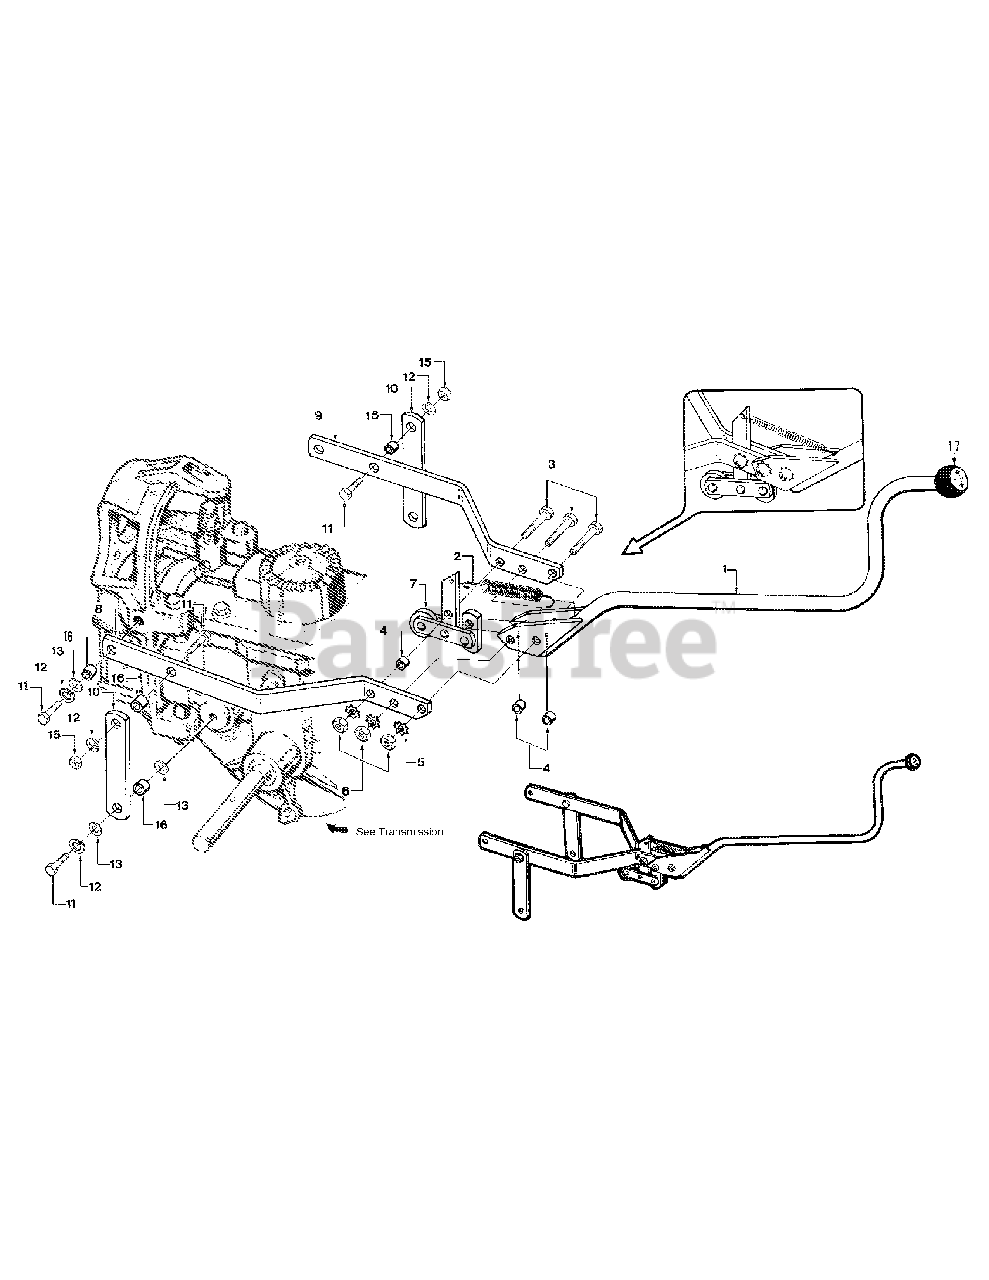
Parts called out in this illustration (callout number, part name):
1	Lever Assembly-Wheels/Tines/PTO Drive (Includes Ref. 17)
2	Spring-clutch pawl
3	Bolt-hex hd.,5/16-18 x 1-1/2"
4	Bushing-3/8"
5	Lockwasher external tooth, 5/16"
6	Nut,hex, 5/16"-18
8	Yoke, left side
9	Yoke, right side
10	Link, yoke pivot, left & right, 6-7/8" long
11	Bolt-hex hd., 3/8-16 x 1"
12	Lockwasher, spring lock, 3/8"
13	Washer flat, 3/8", S.A.E.
15	Nut hex, 3/8"-16
16	Bushing, spacer, 19/64" (.300")
17	Knob
